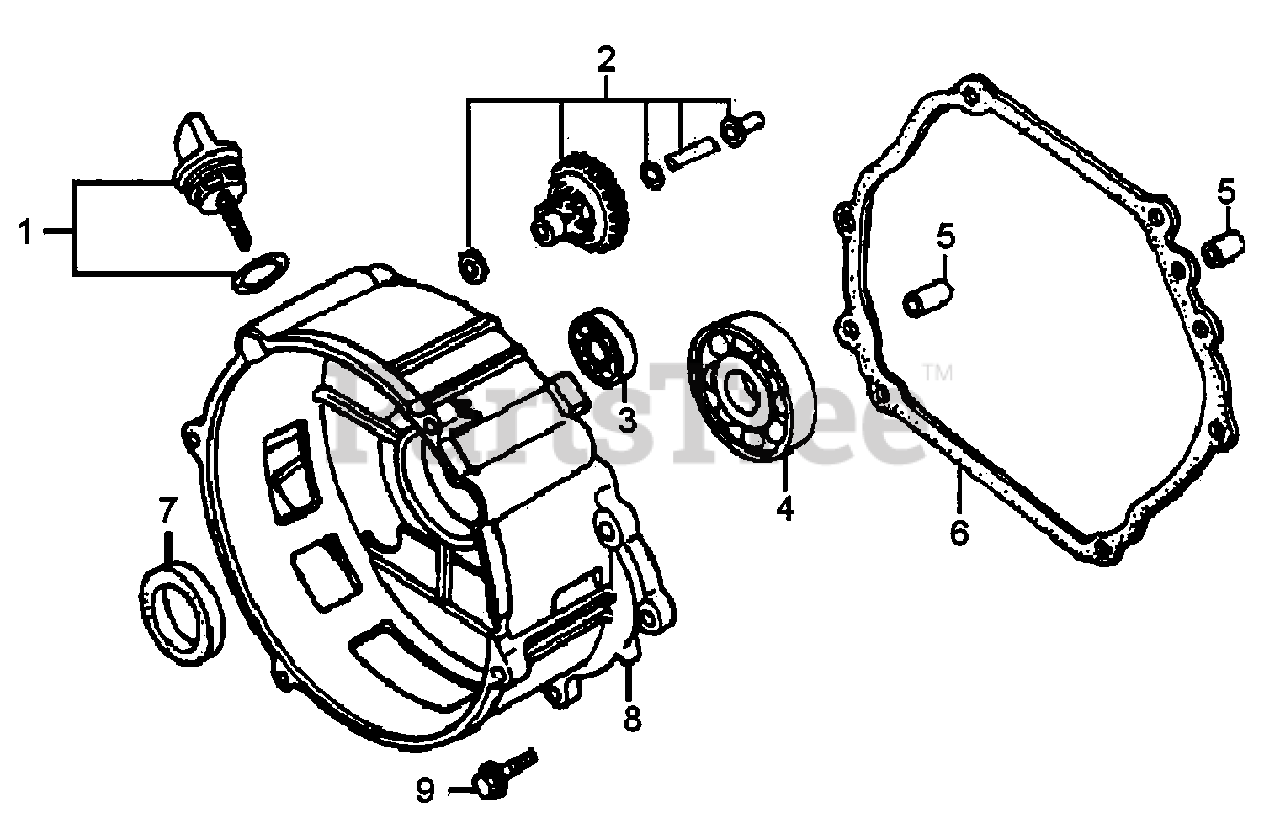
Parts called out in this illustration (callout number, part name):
1	CAP ASSY., DIPSTICK
2	GOVERNOR ASSY.
3	BEARING, RADIAL BALL 6202
4	BEARING, RADIAL BALL 6207
5	PIN, DOWEL 8X12
6	GASKET, CRANKCASE COVER
7	SEAL, OIL
8	COVER, CRANKCASE
9	BOLT, FLANGE 8X40
